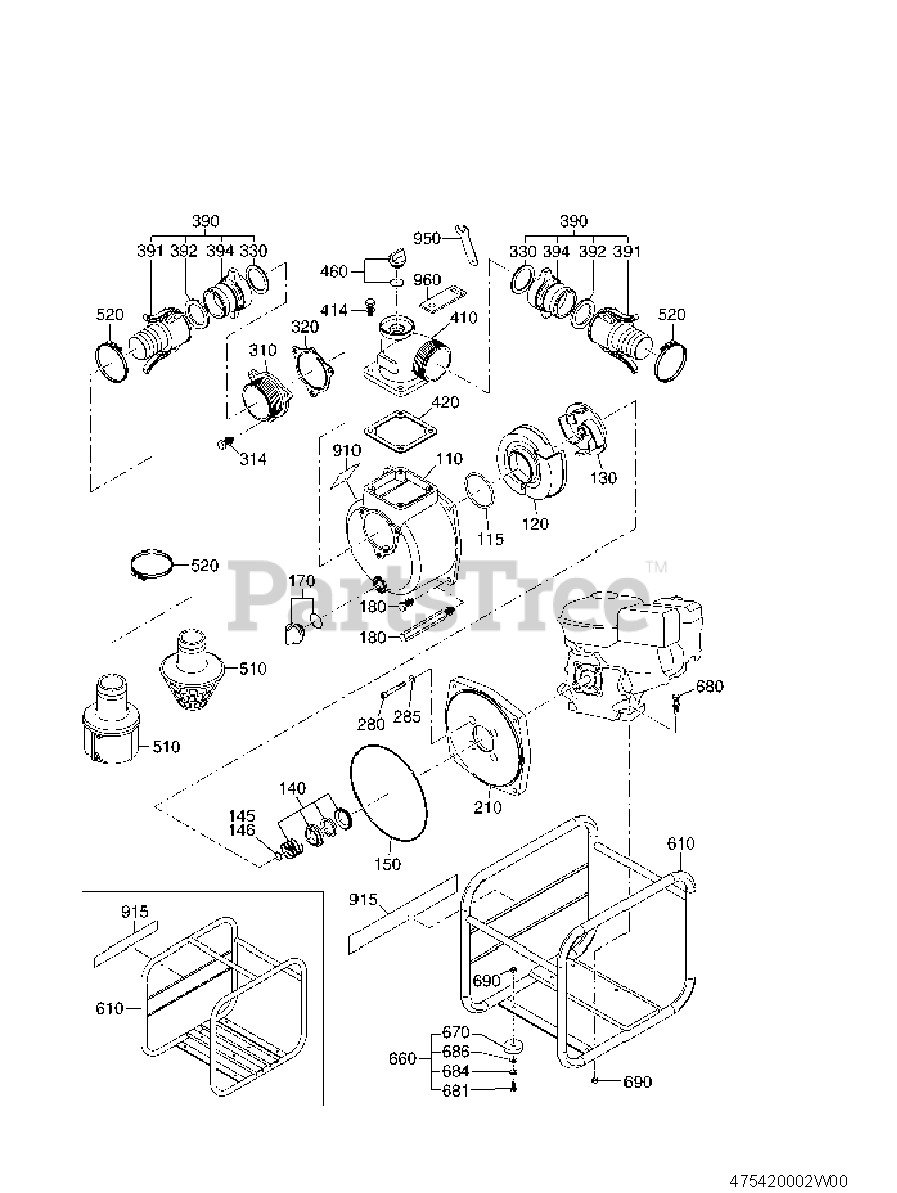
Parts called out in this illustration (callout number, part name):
130	IMPELLER
140	MECHANICAL SEAL
145	ADJUSTING WASHER
146	ADJUSTING WASHER
180	BOLT & WASHER AY
210	FLANGE BRACKET
310	SUCTION FLANGE
314	BOLT & WASHER AY
410	DELIVERY FLANGE
414	BOLT & WASHER AY
420	PACKING, DELVERY
670	CUSHION RUBBER
680	BOLT & WASHER AY
681	BOLT & WASHER AY
910	LABEL(PUMP NAME)
